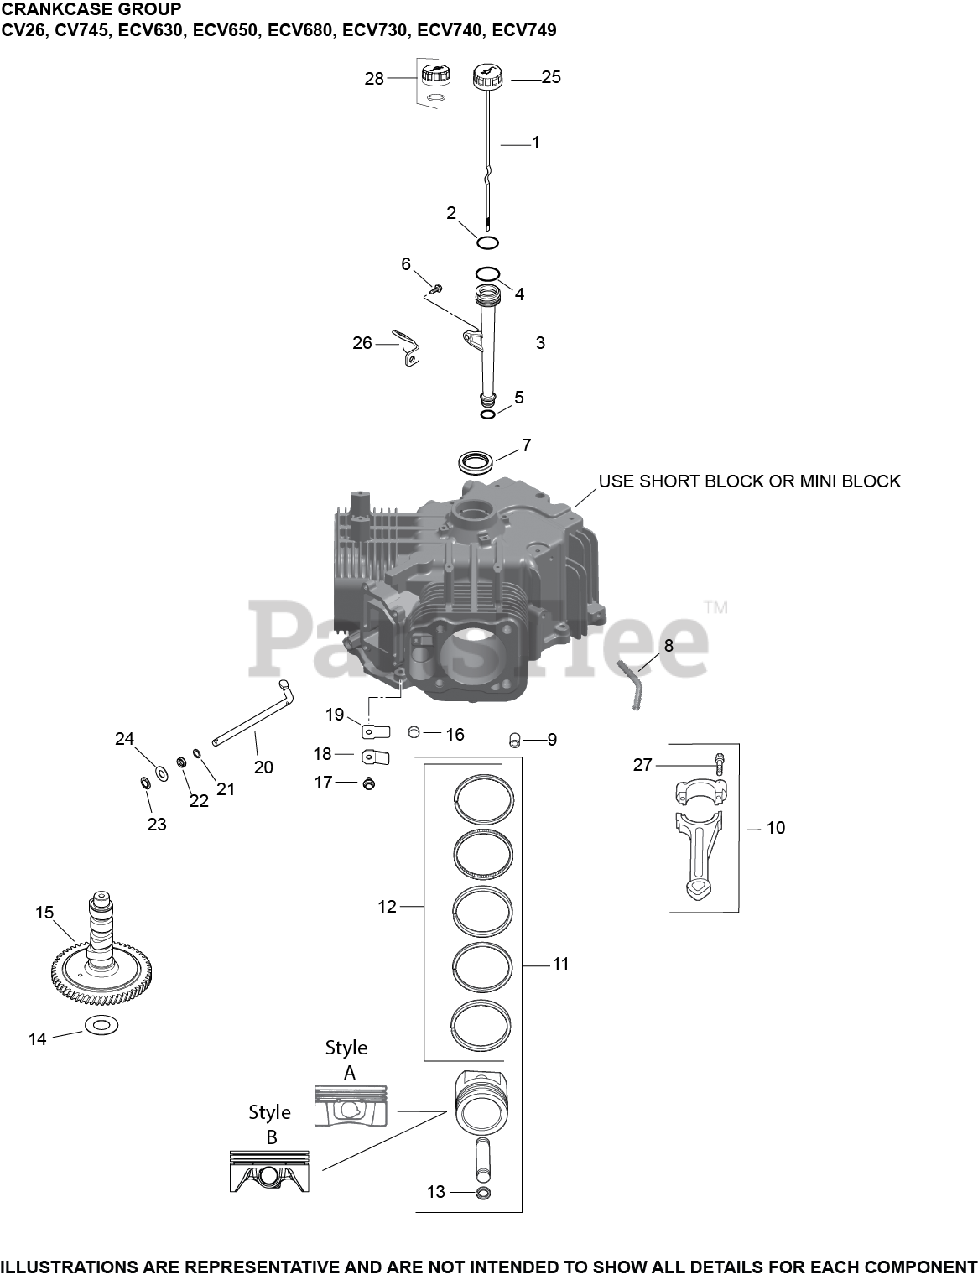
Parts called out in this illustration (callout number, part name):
1	DIPSTICK, ASSY
2	O-RING, DIPSTICK
3	TUBE ASSEMBLY
4	O-RING, UPPER OIL FILL TUBE
5	O-RING, LOWER OIL FILL TUBE
6	SCREW,FLG THD FRM M5X0.8X16-(#25086398S)
7	SEAL, OIL (HELIX LIP)
9	PIN, LOCATING
10	KIT, CONNECTING ROD ASSEMBLY USE 25 067 04-S
11	RING SET (STYLE A)(STD) 1.5MM TOP RING THICKNESS USE PISTON ASSY PER SPEC - Discontinued
11	RING SET (STYLE A) (.08) 1.5MM TOP RING THICKNESS -DISCONTINUED
11	RING SET (STYLE A)(.25)1.5MM TOP RING THICKNESS - USE 24 874 44-S
11	RING SET (STYLE A)(.50)1.5MM TOP RING THICKNESS
11	RING SET (STYLE B) (STD)1.2MM TOP RING THICKNESS
11	RING SET (STYLE B) (.08)1.2MM TOP RING THICKNESS
11	RING SET (STYLE B) (.25)1.2MM TOP RING THICKNESS
11	RING SET (STYLE B) (.50)1.2MM TOP RING THICKNESS
12	PISTON W/RINGS (STYLE A)(STD) - USE 24 874 58-S
12	PISTON W/RINGS (STYLE A)(.08) - DISCONTINUED
12	PISTON W/RINGS (STYLE B)(STD) - RING SET 24 108 26-S
12	PISTON W/RINGS (STYLE B)(.08) - RING SET 24 108 27-S
12	PISTON W/RINGS (STYLE B)(.25) - RING SET 24 108 28-S
12	PISTON W/RINGS (STYLE B)(.50) - RING SET 24 108 29-S
13	RETAINER, PISTON PIN
15	KIT, CAMSHAFT
16	PLUG, CUP
17	SCREW, FLG THD FRM M5X.8X10
18	RETAINER, BREATHER REED
19	REED, BREATHER
20	SHAFT, GOVERNOR CROSS
21	WASHER, FLAT 11/32"
22	SEAL, GOVERNOR CROSS SHAFT
23	RETAINER, RING
24	WASHER, FLAT 9 MM
27	KIT, ROD BOLTS
28	KIT, OIL FILL CAP (BLACK)
